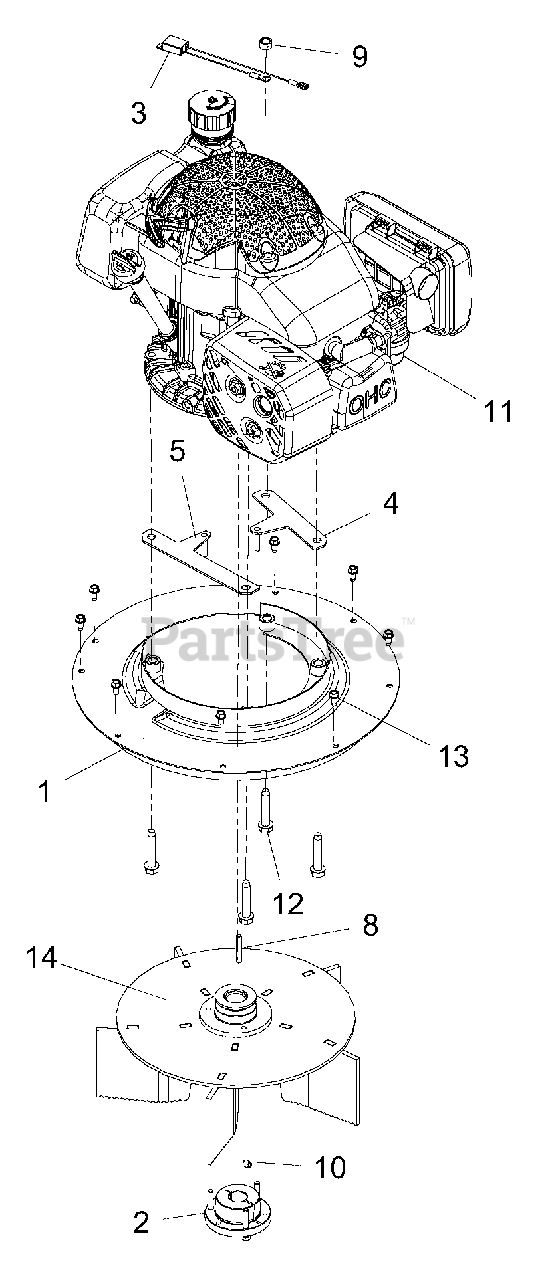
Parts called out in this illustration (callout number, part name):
1	WMT-ENGINE PLATE
2	BUSHING, TAPER-SPLIT 7/8"(SDS)
2	@WSHR-LK .25X.062 REG YWZC
2	BLT-HEX .25-20X1.5 FTHD GR5 ZC
3	WIRE HARNESS-APV
4	WLDMT, BRKT - APV BELT FNGR L
5	WLDMT, BRKT - APV BELT FNGR R
8	KEY-SQ .188X1.50X.188
9	@NUT-LK-CTR .38-16 YWZC
10	SCR-SET .31-18X.38 SKHCUPDL
11	ENGINE,SUBARU EA190 (CARB)
12	SCR-TAP .38-16X2.00 HWH TR YZ
13	SCR-TAP .25-20X.50 HWH TR YWZ
14	WLDMT,IMPELLER - APV TAPER
